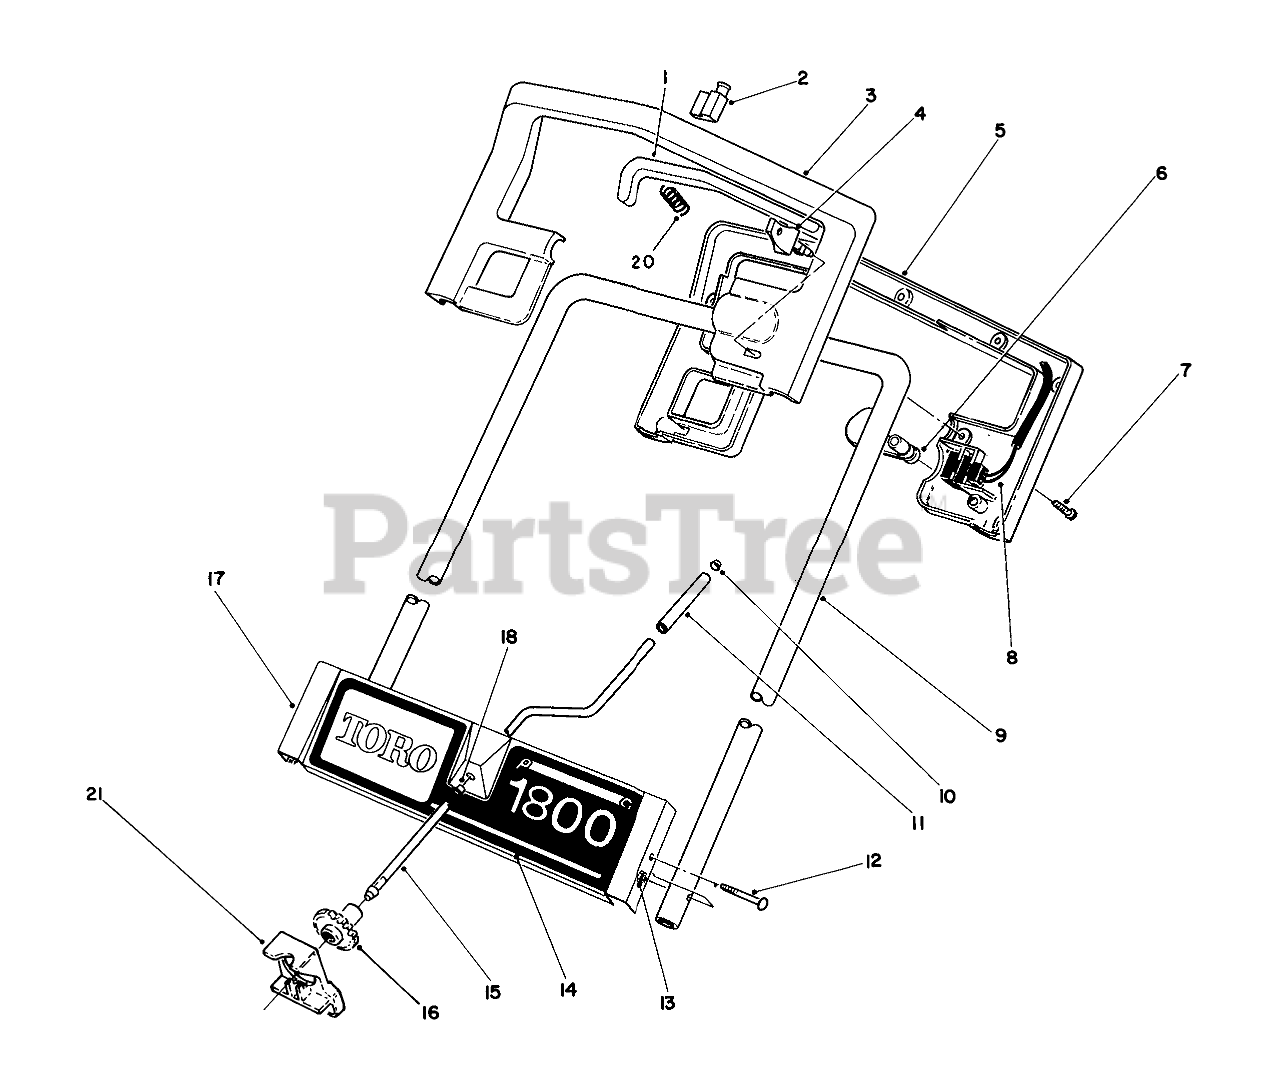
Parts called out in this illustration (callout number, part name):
1	Bar-Switch
2	SWITCH
3	Handle-Control, Upper
5	Handle-Control, Lower
6	Tab-Lock
7	Screw
8	Cord-Supply
9	Tube-Handle, Upper
10	PUSHNUT-CAP, WASHER
11	Sleeve-Crank, Chute
12	Screw-HH
13	NUT-LOCK, NI
14	DECAL - ESCUTCHEON
15	Rod-Crank, Chute
16	Gear-Crank, Chute
17	Plate-Escutcheon
18	Bushing-Nyliner
20	Spring
21	Brake-Gear
